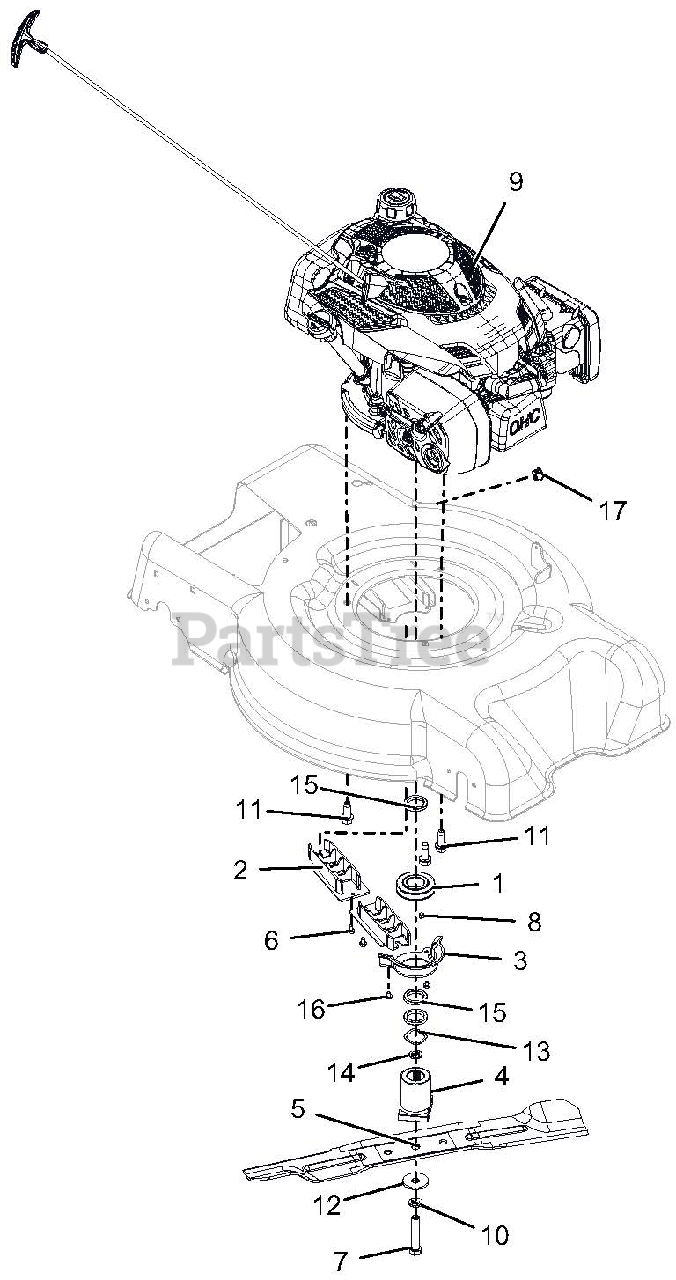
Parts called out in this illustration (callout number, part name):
1	PULLEY,MACHINED POWDER METAL
2	GUIDE, BELT INNER
3	GUIDE, BELT CRANK
4	ADAPTER, BLADE
5	BLADE, MOWER 21" HIGH LIFT
6	SCR-TAP 10-24X.375 PRE-COAT 80
7	@BLT-HEX .4375-20X2.25 GR8 YWZ
8	KEY-SQ .188X.188X.250
9	ENGINE, SUBARU 175CC VERT
10	@WSHR-LK .44X.109 REG YWZC
11	@SCR-TAP .38-16X1.00 HWH TR YZ
12	WSHR-FL-STL .4375X1.50X.125 YZ
13	WASHER - WAVE 1.09X1.37X.016
14	WSHR-FL-STL .459X.750X.105 YZC
15	SPCR, 1.00 X 1.375 X .179
16	SCR-TAP 10-24X.25 CRSLPH TR YZ
17	PLUG, DOME-BLACK, .625 DIA
